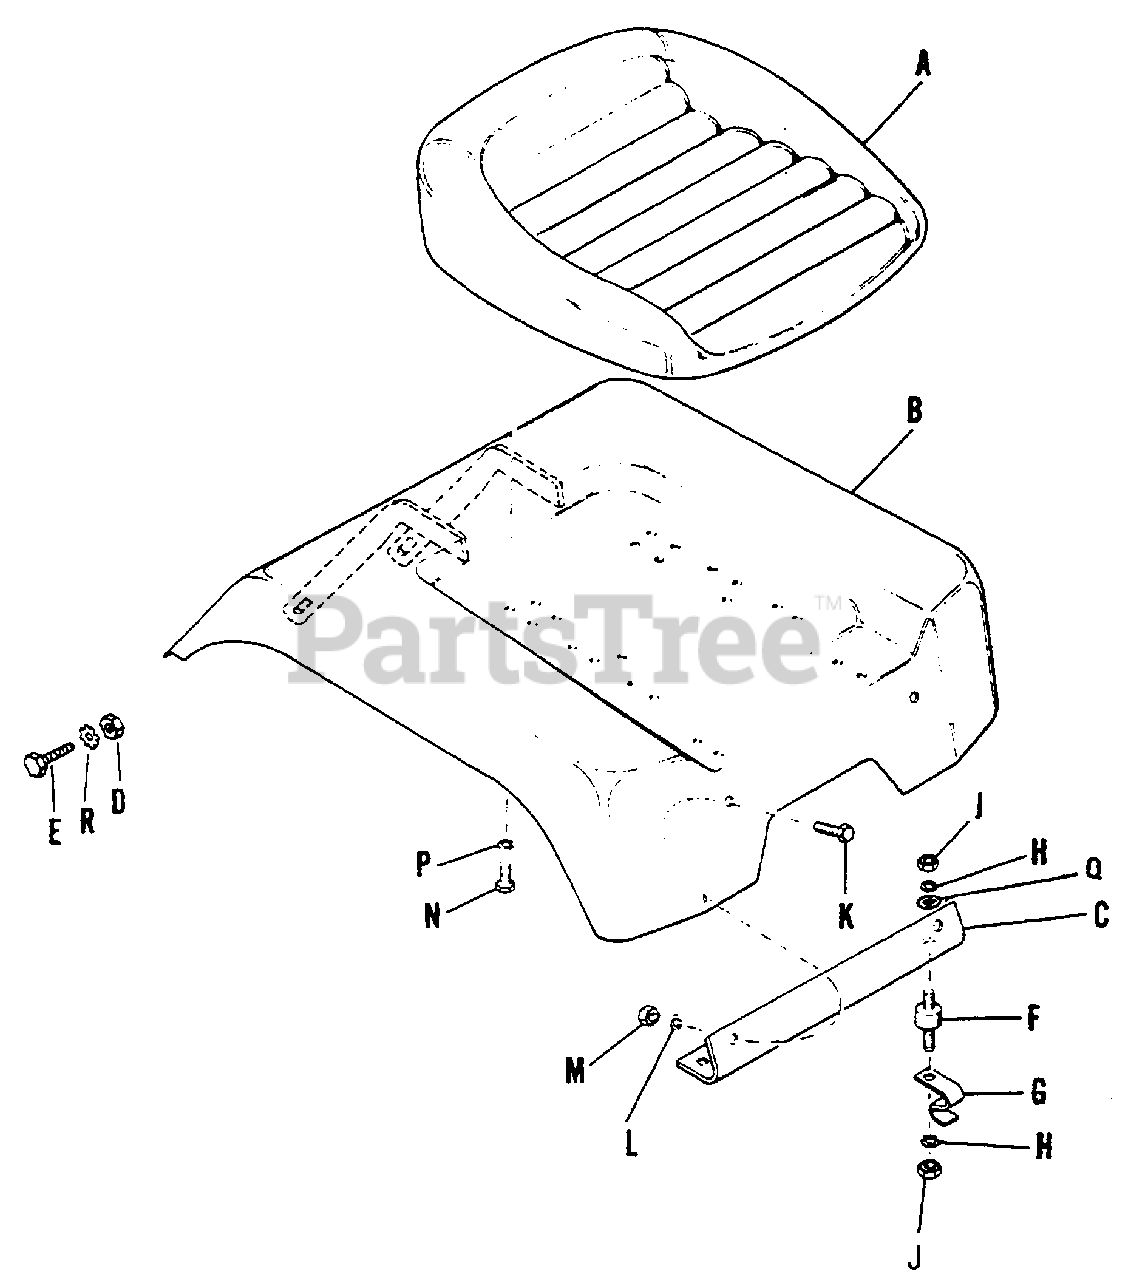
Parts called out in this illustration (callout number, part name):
A	Seat Assembly
B	Seat Deck Assembly
C	Seat Deck Bracket, Front
D	Hex, Locknut, Full, 3/8Ó - 16
E	Hex, Head Capscrew, 3/8Ó - 16 x 1-1/4Ó
F	Cushion Connector, Front
G	Spring Clip
H	Lock Washer, 5/16Ó
J	Hex, Nut, full, 5/16Ó - 18
K	Hex, Head Capscrew, 5/16Ó - 18 x 5/8Ó lg.
L	Lockwasher, 5/16Ó
M	Hex, Nut, Full, 5/16Ó - 18
N	Hex, Head Capscrew, 5/16Ó - 18 x 5/8Ó lg.
P	Lockwasher, 5/16Ó
Q	Plain Washer, 1/4Ó
R	Lockwasher, 5/16
